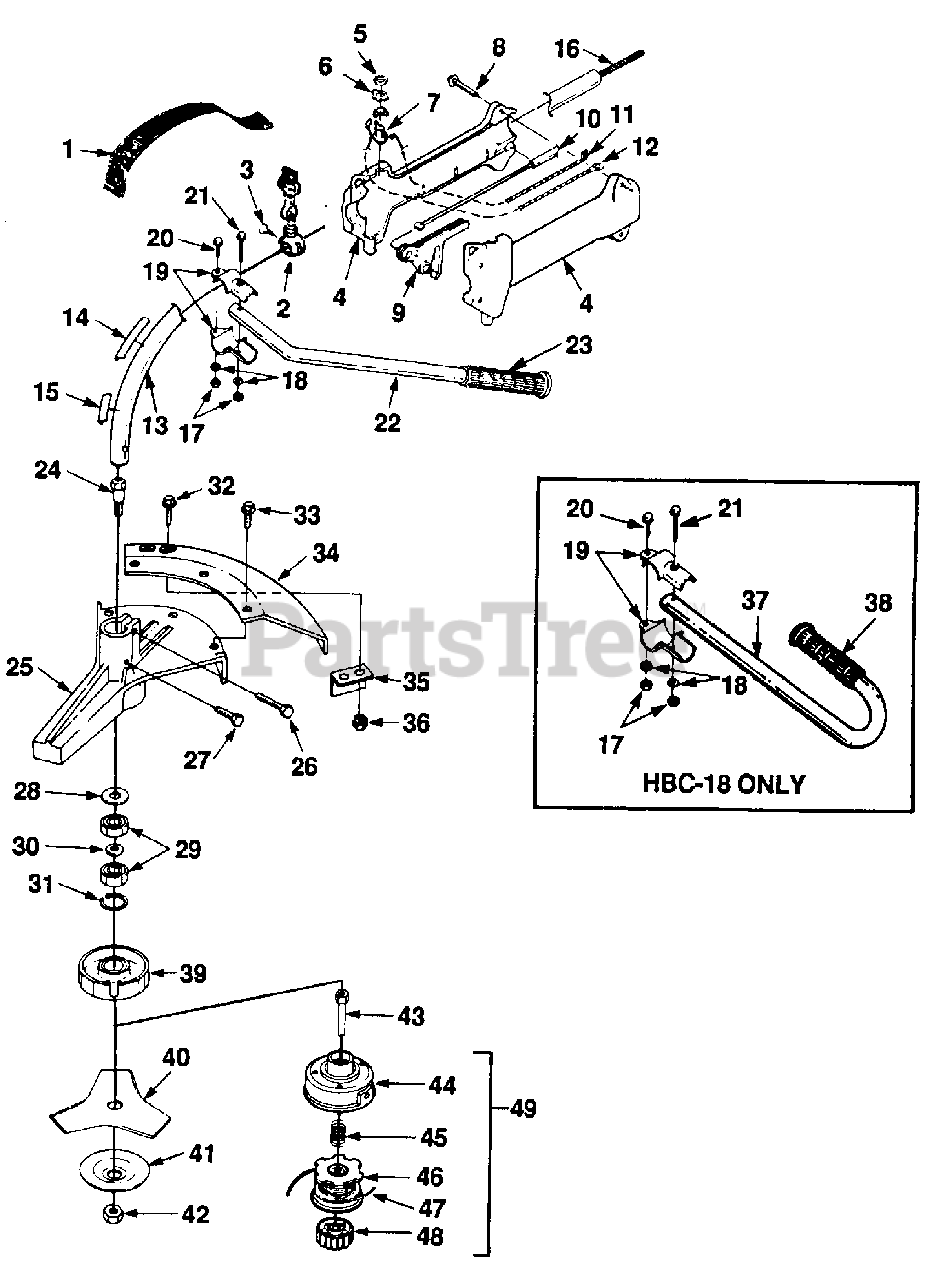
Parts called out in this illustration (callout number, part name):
1	HARNESS w/Connector
2	BRACKET-Hanger
3	SCREW-Thumb (10-24 X 1/2")
4	HANDLE GRIP ASSEMBLY
5	NUT-Toggle Switch
6	PLATE-Indicating
7	SWITCH-Toggle
8	SCREW-Plastite (#8 X 3/4")
9	TRIGGER
10	CABLE-Throttle
11	LEAD-Electrical
12	LEAD-Ground
13	HOUSING-Drive Shaft (Black)
14	DECAL-Starting Instructions
15	DECAL-Warning
16	SHAFT-Flex
17	NUT (1/4-20)
18	WASHER (1/4")
19	CLAMP-Handle Bar
20	SCREW-Sems Hex Hd. (1/4-20 X 1")
21	SCREW-Sems Hex Hd. (1/4-20 X 1 1/2")
22	HANDLE BAR (ST-185BC)
24	SHAFT-Spindle
25	HOUSING-Lower Bearing
26	SCREW-Sems Hex Hd. (1/4-20 X 1")
27	SCREW-Mach Hex Hd. (10-24 X 3/8")
28	WASHER-Thrust
29	BEARING-Ball
30	SPACER-Bearing
31	RING-Retaining
32	SCREW-Mach Hex Hd. (10-24 X 3/8 )
33	SCREW-Mach Hex Hd.(1/4-20 X 1/2")
34	DEFLECTOR-Grass
35	BLADE-Cut-Off
36	NUT (10-24)
37	HANDLE BAR ("J") (HBC-18)
39	WASHER-Flanged
40	BLADE-Tri-Arc (8")
41	WASHER-Cupped
42	NUT-Hex Locking (R.H.)
43	CONNECTOR-Drive
44	HOUSING & EYELET (Dual Line)
45	SPRING-Compression
46	SPOOL & STRING (Dual Line) (ST-185BC)
47	LINE-Replacement (ST-185BC) (.080" Dia. 1 lb. Box)
48	RETAINER-Spool (R.H. Thread)
49	STRING HEAD COMPLETE (.080 Line) (ST-185BC)
